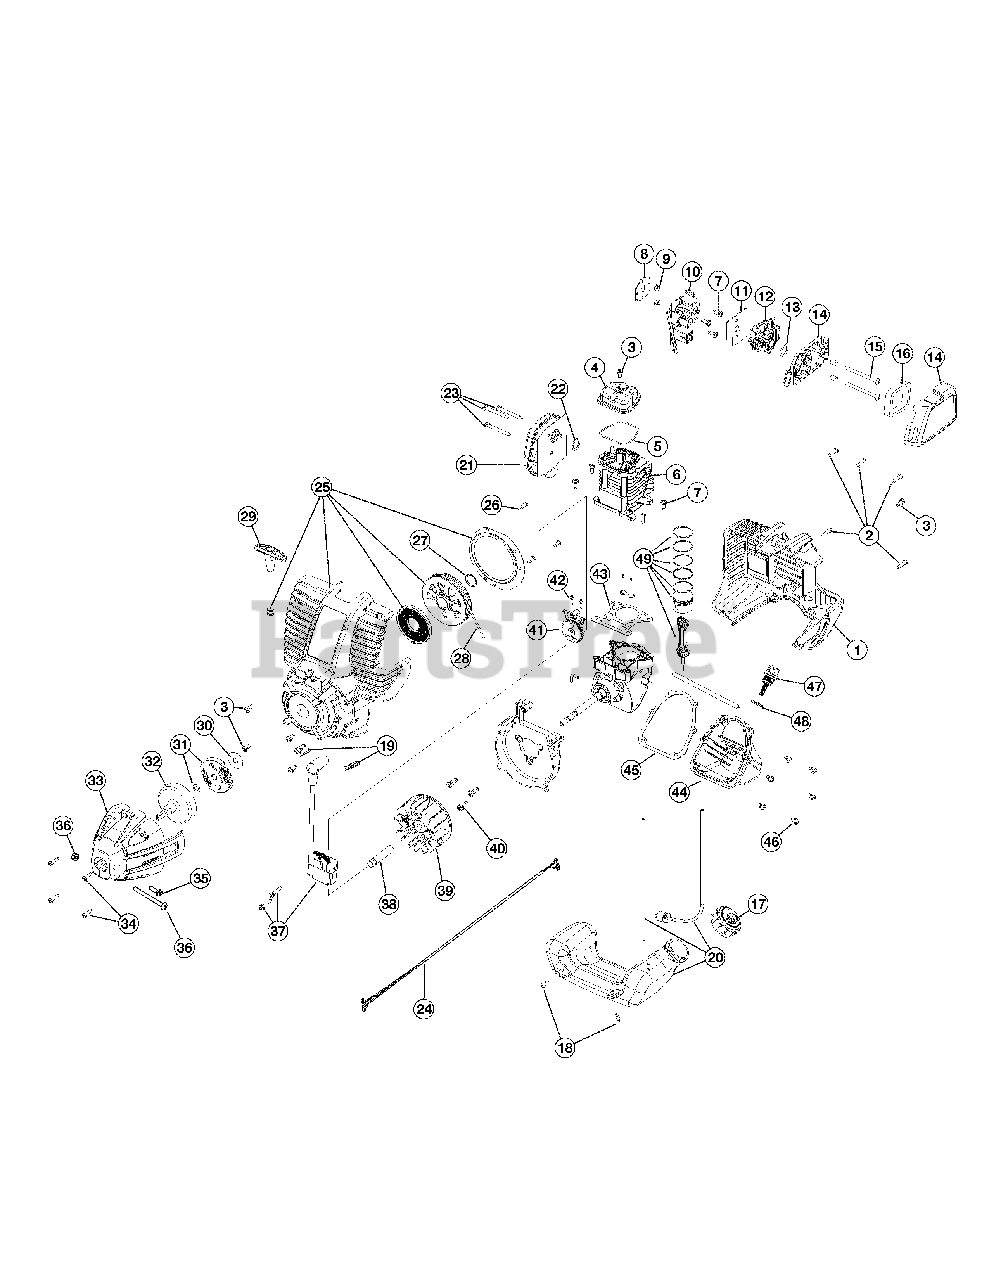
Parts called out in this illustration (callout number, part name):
1	Engine Cover
4	Valve Cover
5	Valve Cover Gasket
6	Cylinder Assembly
7	Cylinder Screw
8	Insulator Gasket
10	Insulator
11	Carburetor Gasket
12	Carburetor w/Primer
13	Carburetor O-Ring
14	Air Filter Cover Assembly
15	Air Filter Mounting Screw
16	Air Filter
17	Fuel Cap
19	Clip Nut
20	Fuel Tank Assembly
21	Muffler Assembly
22	Muffler Gasket
23	Muffler Mounting Screw
24	Lead Wire
25	Starter Housing Assembly
26	Plate Screw
27	Push Nut
29	Pull Handle
30	Washer
31	Clutch Assembly
32	Clutch Drum
33	Clutch Cover Assembly
34	Cover Screw
35	Anti-Rotation Screw
36	Clamping Screw Assembly
37	Ignition Module Assembly
38	Spacer
39	Flywheel
40	Shroud Screw
41	Cam Bracket Assembly
42	Cam Bracket Screw
43	Cylinder Gasket
44	Oil Pan
45	Oil Pan Gasket
46	Oil Pan Screw
47	Dipstick Assembly
49	Piston Assembly
